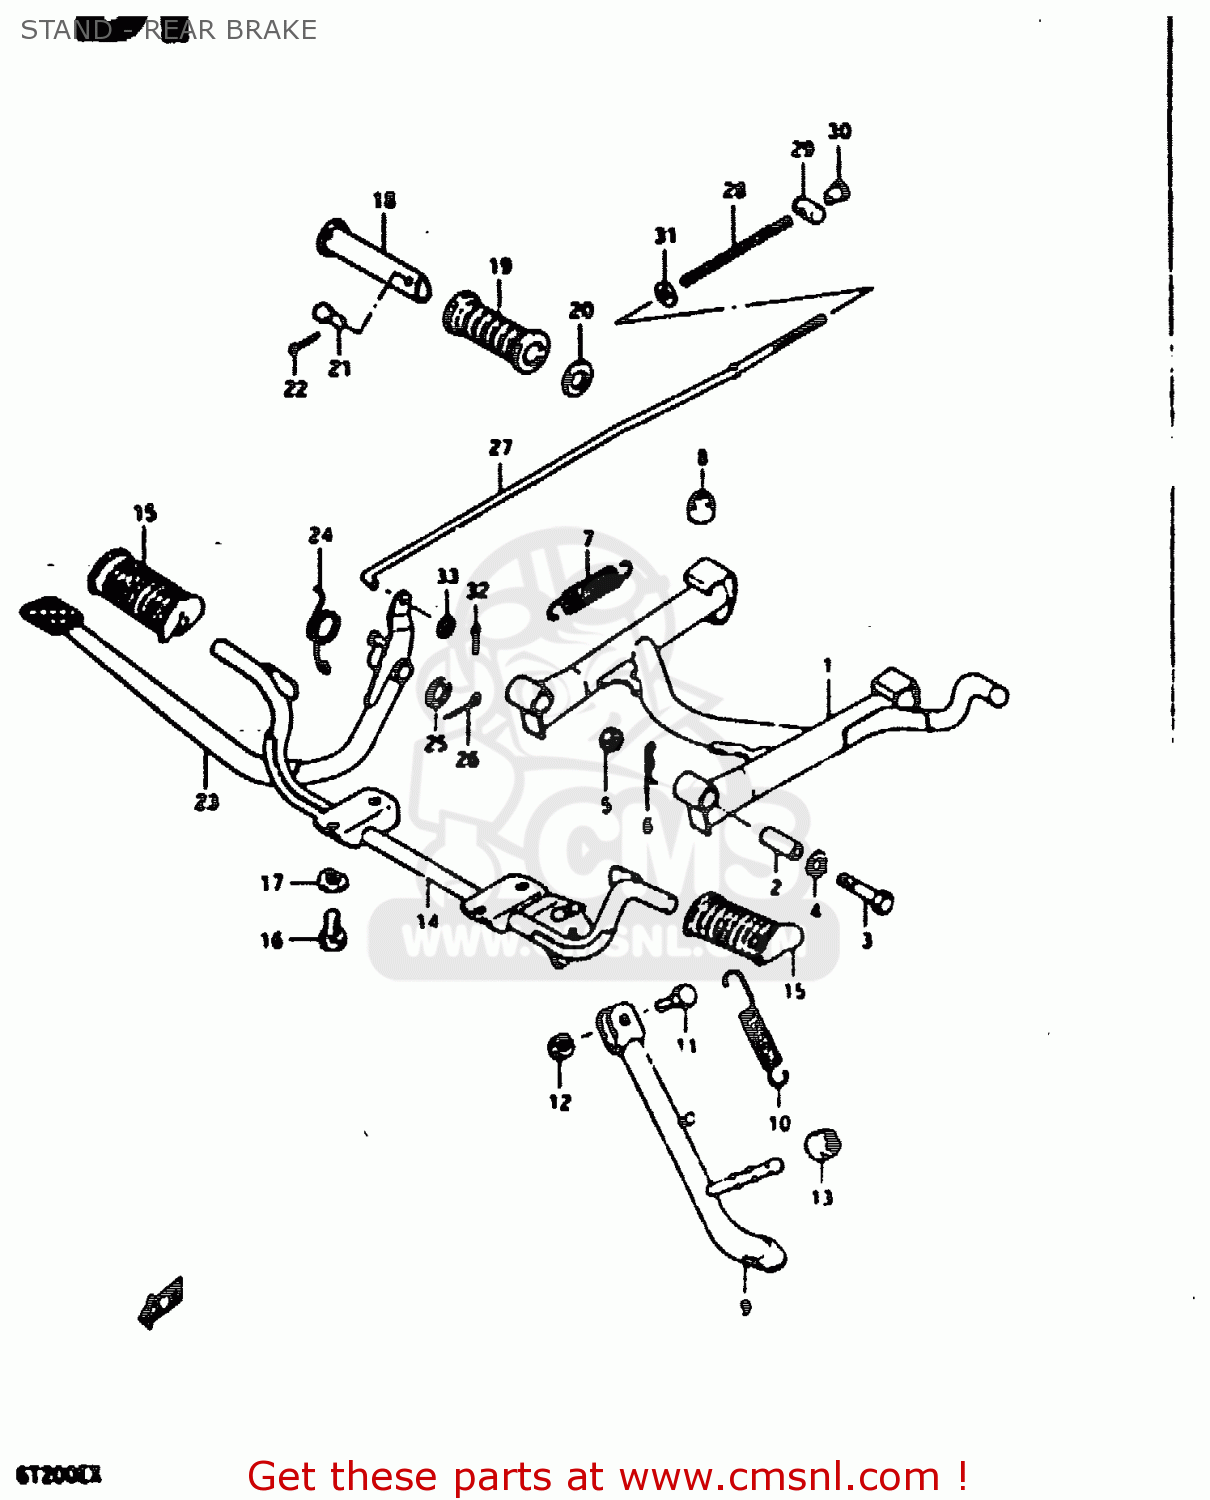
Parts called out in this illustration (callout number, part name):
1	STAND, CENTER
2	SPACER(10.5X16X30)
3	BOLT 10X52
4	LOCK WASHER
5	NUT
6	CLIP
7	SPRING
8	CUSHION
9	STAND, PROP
10	SPRING
11	BOLT
12	NUT
13	CUSHION
14	BAR, FRONT FOOTREST
15	RUBBER,FR FOOTREST
16	BOLT
17	LOCK WASHER
18	BAR,FOOTREST RUBBER
19	RUBBER,PILLION FOOTREST
20	WASHER (19.5X32X2)
21	PIN
22	PIN 20X20
23	PEDAL,BRAKE
24	SPRING
25	WASHER(15.5X26X2.3)
26	COTTER PIN
27	ROD ASSY, REAR BRAKE
28	SPRING
29	PIN
30	NUT
31	WASHER
32	PIN 20X20
33	WASHER
